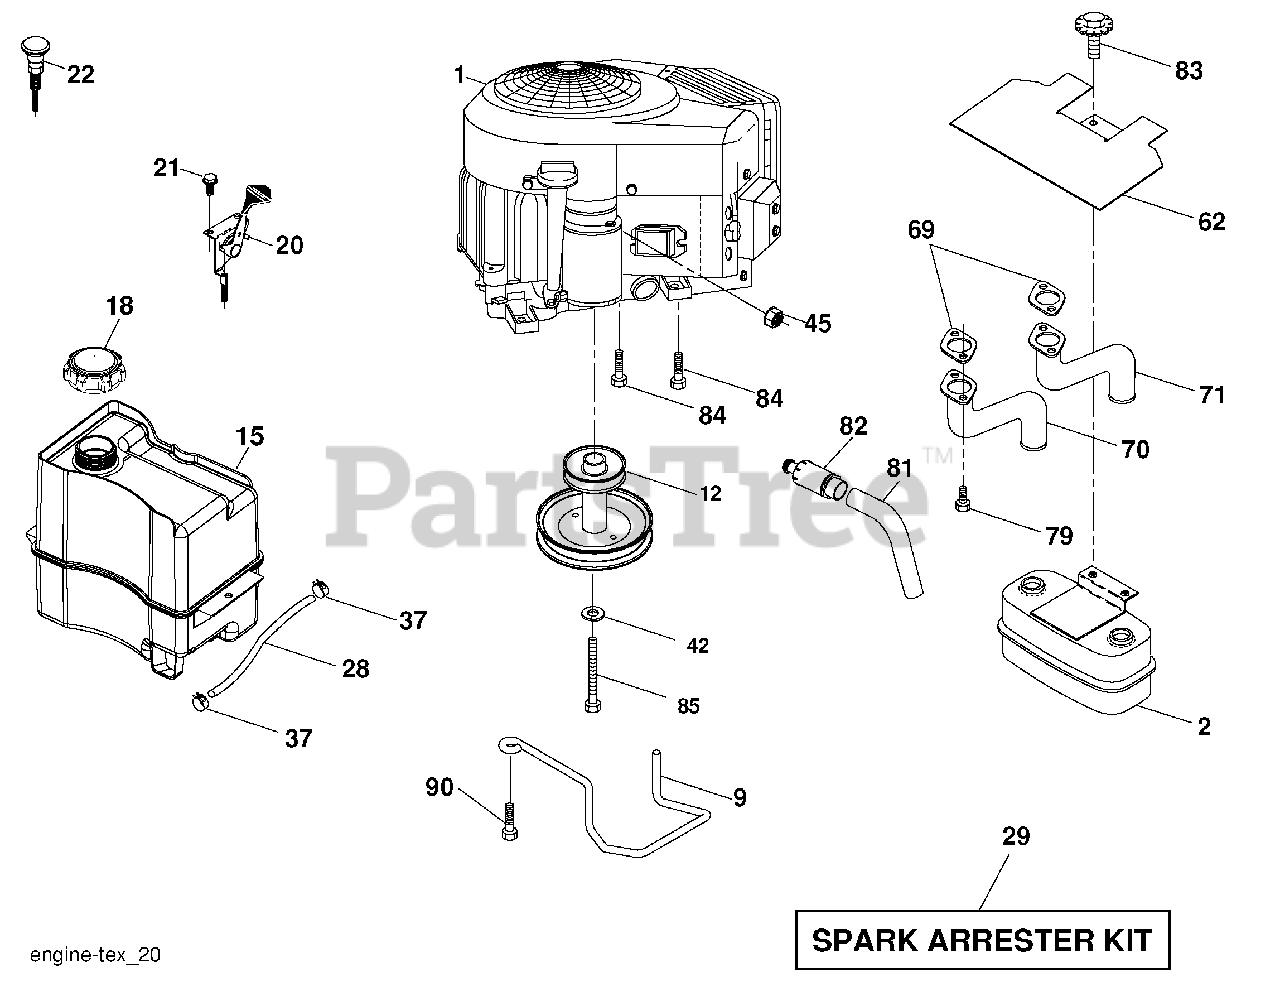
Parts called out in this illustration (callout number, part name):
2	Muffler
9	Keeper Belt Engine
12	Pulley Engine
15	Tank Fuel 3.0
18	Cap Asm
20	Control Throttle
21	Screw 10 x 3/4 Single Lead-Hex
22	Control Choke
28	Fuel Line
29	Spark Arrester Kit
37	Clamp Hose
42	Washer Lock 7/16
45	Nut Keps Hex 1/4-20 unc
62	Shield Heat Muffler
69	Gasket
70	Exhaust Tube RH
71	Exhaust Tube LH
79	Screw Socket Head 5/16-18 x 1
81	Tube Drain Oil Easy
82	Plug Drain Oil
84	Screw 3/8-16 x 1-1/4
85	Bolt Hex 7/16-20 x 4 x 5 Ga.-1.5
87	Bolt 5/16-18 x 3/4
90	Screw 3/8-16 x 1
